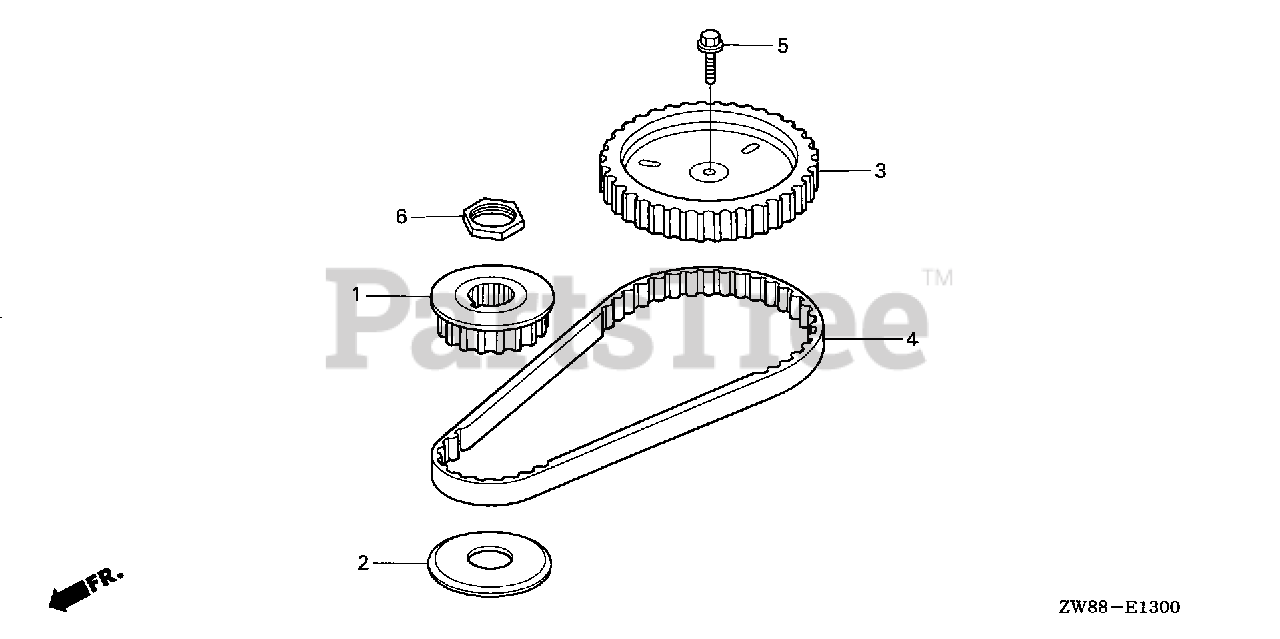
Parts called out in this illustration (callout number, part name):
1	PULLEY, TIMING
2	FLANGE, TIMING PULLEY
3	PULLEY, CAMSHAFT
4	BELT, TIMING (63RU13 B-333)
5	BOLT, FLANGE (6X20)
6	NUT, LOCK (24MM)
